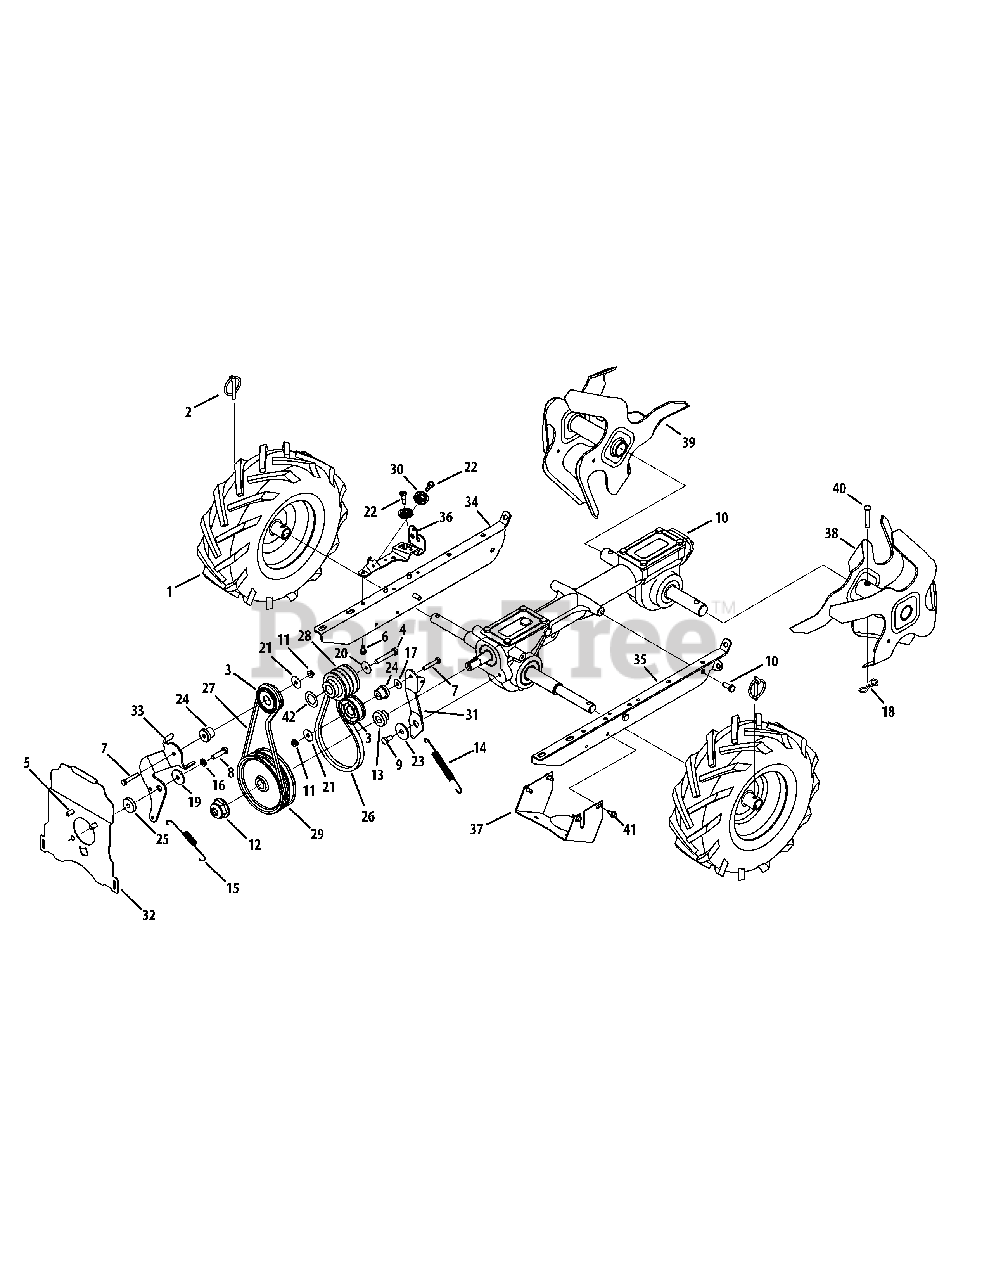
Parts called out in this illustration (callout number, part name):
1	Complete Wheel. Assy., 13 x 5 x 6 (B, C)
2	Click Pin
3	Idler Pulley Assembly
4	Hex Screw, 3/8-24 x 2.00
5	Hex Screw, 5/16-24 x .625
6	Self Tapping Screw, 1/4-20 x .500
7	Hex Screw, 1/4-20 x 1.50
8	Hex Screw, 5/16-18 x 1.25
9	Hex Screw, 5/16-18 x .75, Patch
10	Transmission Assembly
11	Hex Lock Nut, 1/4-20
12	Nut, 9/16-18, Flange Lock
13	Hub, 5/8 Spline
14	Extension Spring, .480 OD X 5.00 LG
15	Extension Spring, LT5 PTO
16	Lock Washer, 5/16
17	Washer, .28 x .74 x .063
18	Internal Cotter Pin
19	Flat Washer, .330 X 1.25 X .120
20	Bell Washer, .396 x 1.140 x .095
21	Flat Washer, .265 x 1.0 x .030
22	Shoulder Screw, .342 x .335 1/4-28
23	Pivot Idler Spacer
24	Shoulder Spacer, .260 x .785 x .538
25	Pivot Idler Spacer
26	V-Belt
27	V-Belt
28	Engine Pulley
29	Transmission Pulley
30	Cable Roller
31	Idler Bracket, Forward
32	Cover Plate
33	Idler Bracket, Reverse
34	Mounting Frame, RH
35	Mounting Frame, LH
36	Pulley Bracket
37	Pulley Shield
38	Tine Assembly, LH
39	Tine Assembly, RH
40	Clevis Pin, .375 x 1.75
41	Hex Washer Screw, 1/4-14 x .625
42	Flat Washer, .760 x 1.500 x .120
